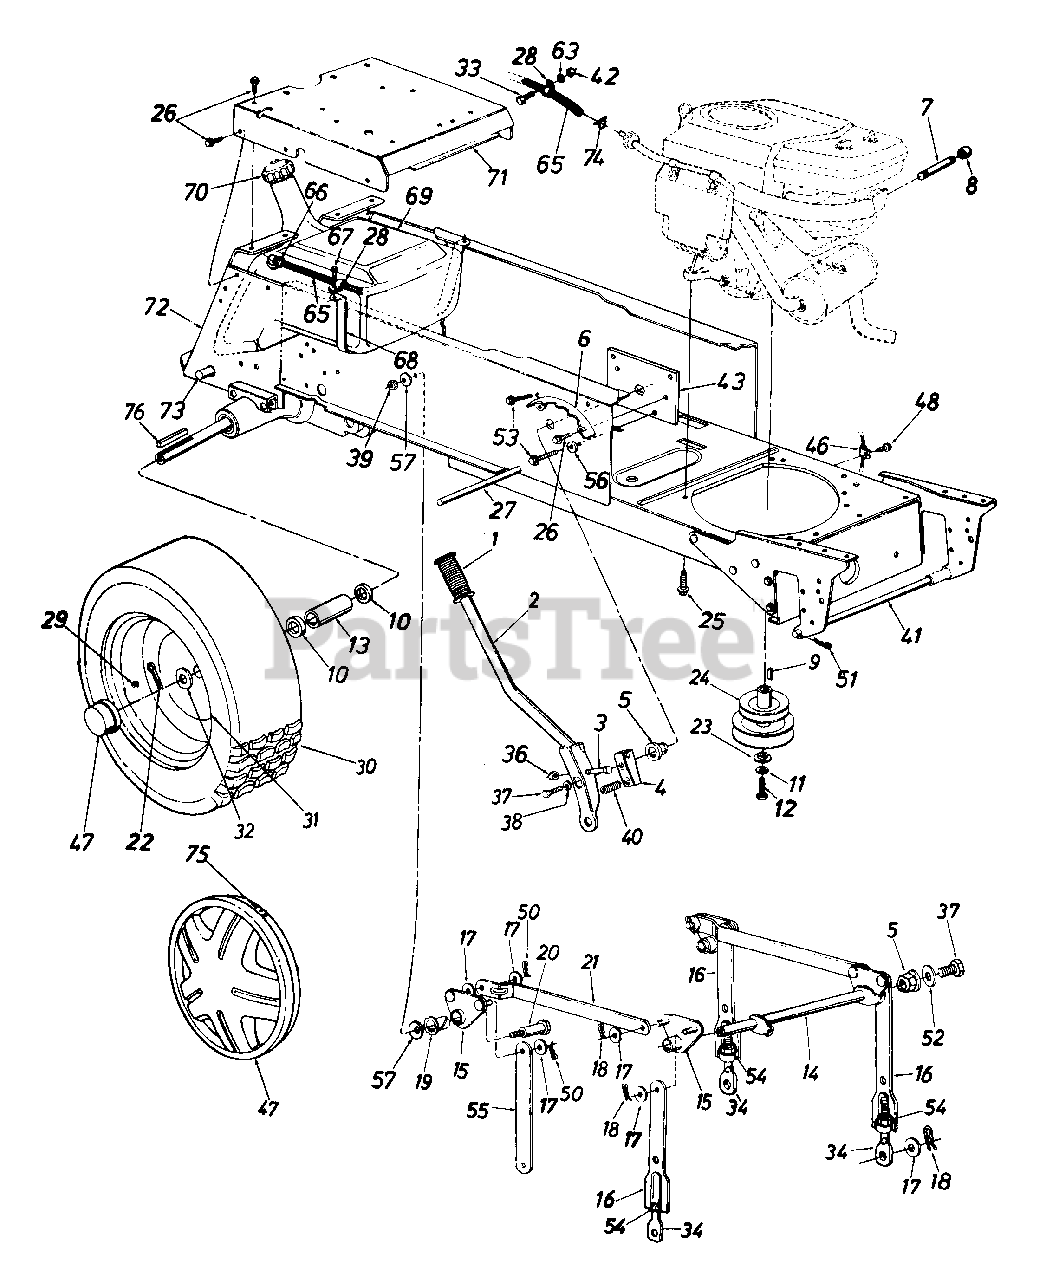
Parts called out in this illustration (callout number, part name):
1	Grip
2	Lift Handle Ass'y.
3	Hex Bolt 5/16-18 x 1.5" Lg.
4	Lift Shaft Drive
5	Plastic Hex Brg. 5/8" I.D.
8	Pipe Cap 3/8-18 Npt.
9	Sq. Key 1/4" x 1/4" x 1.50" Lg.
10	Fl-Wash. 1.03" I.D. x 1.62" O.D.
11	L-Wash. 7/16" 1.D.
12	Hex Scr. 7/16-20 x 1.50" Lg.
13	Spacer 1.0" I.D. x 1.25" O.D.
14	Lift Shaft Ass'y.
15	Lift Pivot Brkt. Ass'y.
17	Fl-Wash. 1/2" I.D. x 1.00" O.D. x .090"
18	Hairpin Cotter
19	Nyliner 5/8" I.D. x .88" Lg.
20	Shld. Bolt 5/8" Dia. x .96" Lg. 3/8-16
23	Flat Wash. .44" I.D. x 1.25" O.D. x .17"
24	Two-Step Engine Pulley
25	Hex Wash. Hd. Scr. 3/8-16 x 1.25" Lg.
26	Hex Thd. Rolling Scr. 5/16-18 x .75" Lg.
27	Running Board Rod
28	Clamp
29	Air Valve
30	Rear Wheel Ass'y. Comp.
31	Rear Wheel Rim Only
33	Hex Bolt 1/4-20 x .62" Lg.
34	Eye Bolt Adj. Link 1/2-13 Thd.
36	Hex Cent. L-Nut 5/16-18 Thd.
37	Hex Bolt 5/16-24 x .62" Lg.
38	L-Wash. 5/16" I.D.
39	Hex Top L-Nut 3/8-16 Thd.
40	Compression Spring
41	Deck Connecting Rod
42	Hex Nut 1/4-20 Thd.
47	Hub Cap
48	Hex Wash. Hd. TT-Tap Scr. 1/4-20 x .5" Lg.
50	Cotter Pin .09 Dia. x 1.0" Lg.
51	Int. Cotter Pin
52	Flat Wash..34" I.D. x 1.12" O.D. x .125"
53	Hex Wash. Hd. AB-Tap Scr .5/16-24 x .5" Lg.
54	Hex Nut 1/2-13 Thd.
56	Fl-Wash. .344" I.D.
57	Bell-Wash. .4" I.D. x 1.13" O.D.
63	L-Wash. 1/4" I.D.
65	Fuel Line 46" Lg.
66	Hose Clamp
67	Hex AB-Tap Scr. 1/4 x .62" Lg.
68	Fuel Tank Strap
69	Gas Tank
70	Gas Gauge
74	Hose Clamp
75	Spring Clip
76	Sq. Key 1/4" x 3" Lg.
